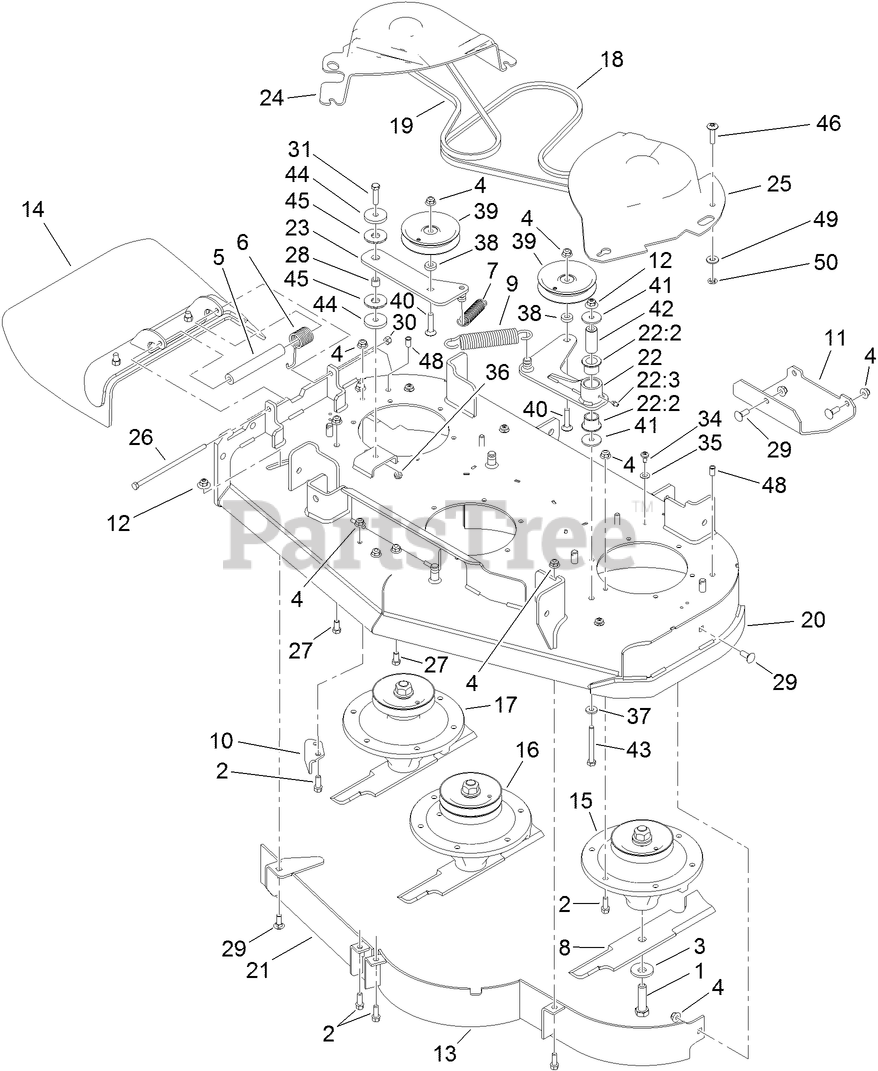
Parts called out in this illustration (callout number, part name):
1	SCREW-BLADE
2	SCREW-HWH
3	Washer-Blade Bolt, Heavy
4	NUT-HF, NI
5	SPACER
6	SPRING-TORSION
7	SPRING-EXTENSION
8	BLADE-14 INCH (HIGH SAIL)
9	SPRING-EXTENSION
10	BAFFLE-DISCHARGE
11	PLATE-SKID
12	NUT-FLANGE, NI
13	BAFFLE ASM
14	DEFLECTOR ASM
15	SPINDLE ASM
16	SPINDLE ASM
17	SPINDLE ASM
18	BELT-V
19	BELT-V
20	DECK ASM
21	FRONT BAFFLE ASM
22	IDLER ARM ASM
22:2	BUSHING
22:3	FITTING-LUBE, 45 DEG
23	IDLER ARM ASM
24	COVER-BELT, RH
25	COVER-BELT, LH
26	SCREW-HH
27	SCREW-HH
28	BUSHING-LEVER, LIFT
29	BOLT-CARR
30	NUT-LOCK, NI
31	SCREW-HH
34	SCREW-SHOULDER
35	WASHER-THRUST
36	NUT-LOCK, NI
37	SPACER
38	SPACER
39	PULLEY-IDLER
40	SCREW-CARR
41	WASHER
42	SPACER-PLAIN
43	SCREW-HH
44	WASHER-PLAIN
45	WASHER-FRICTION, COMPOSITE
46	SCREW-TTH
48	INSERT-NUT
49	WASHER-FLAT
50	NUT-RETAINER
